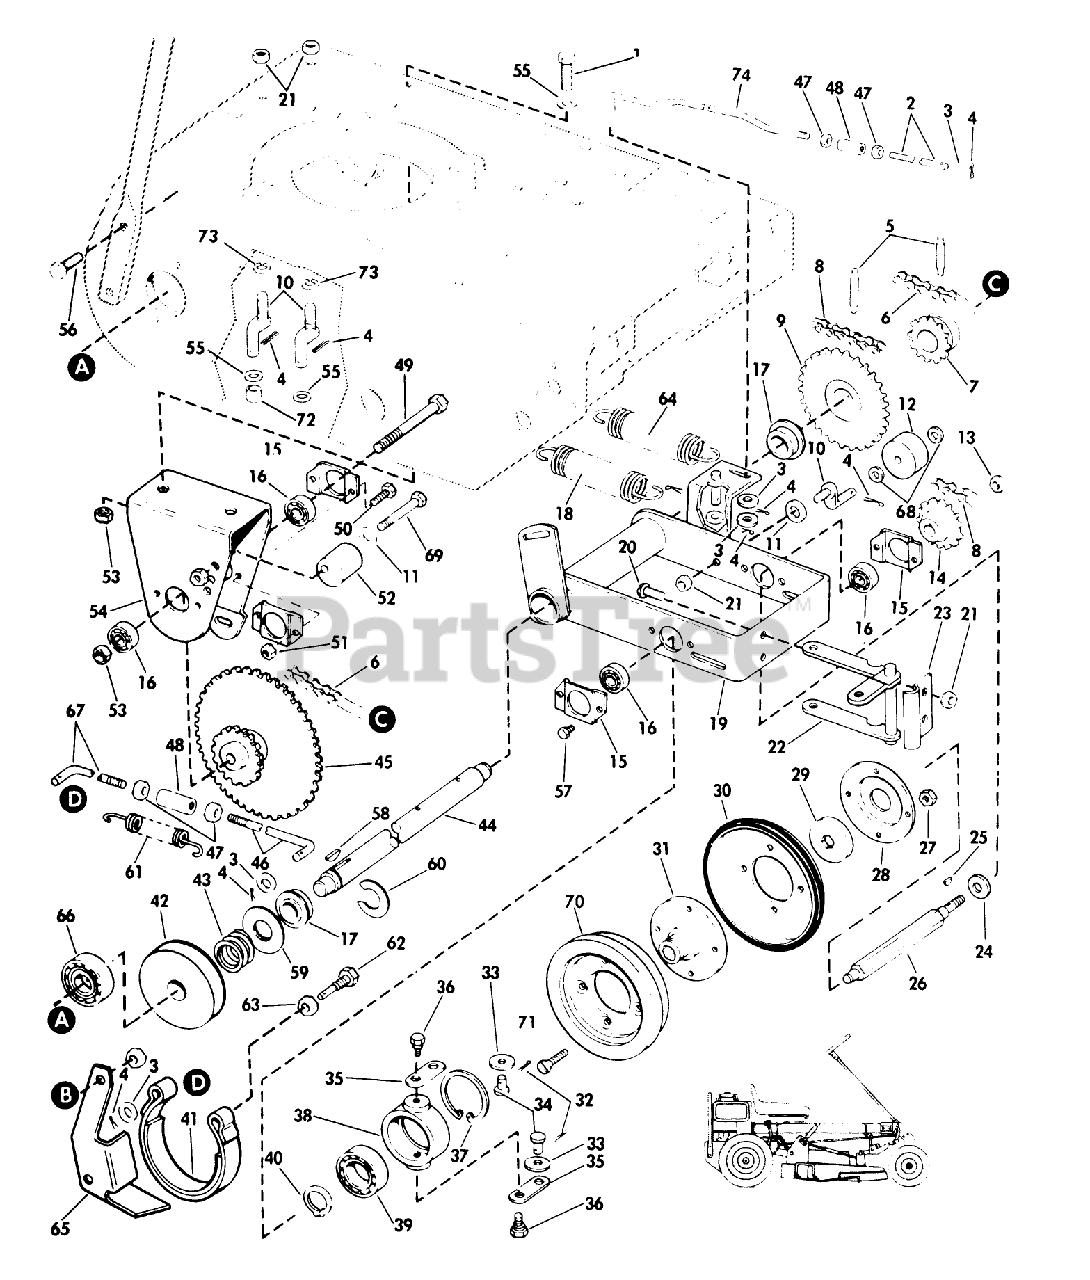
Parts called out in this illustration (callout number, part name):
13	LOCKNUT
47	STOP NUT
53	LOCKNUT
